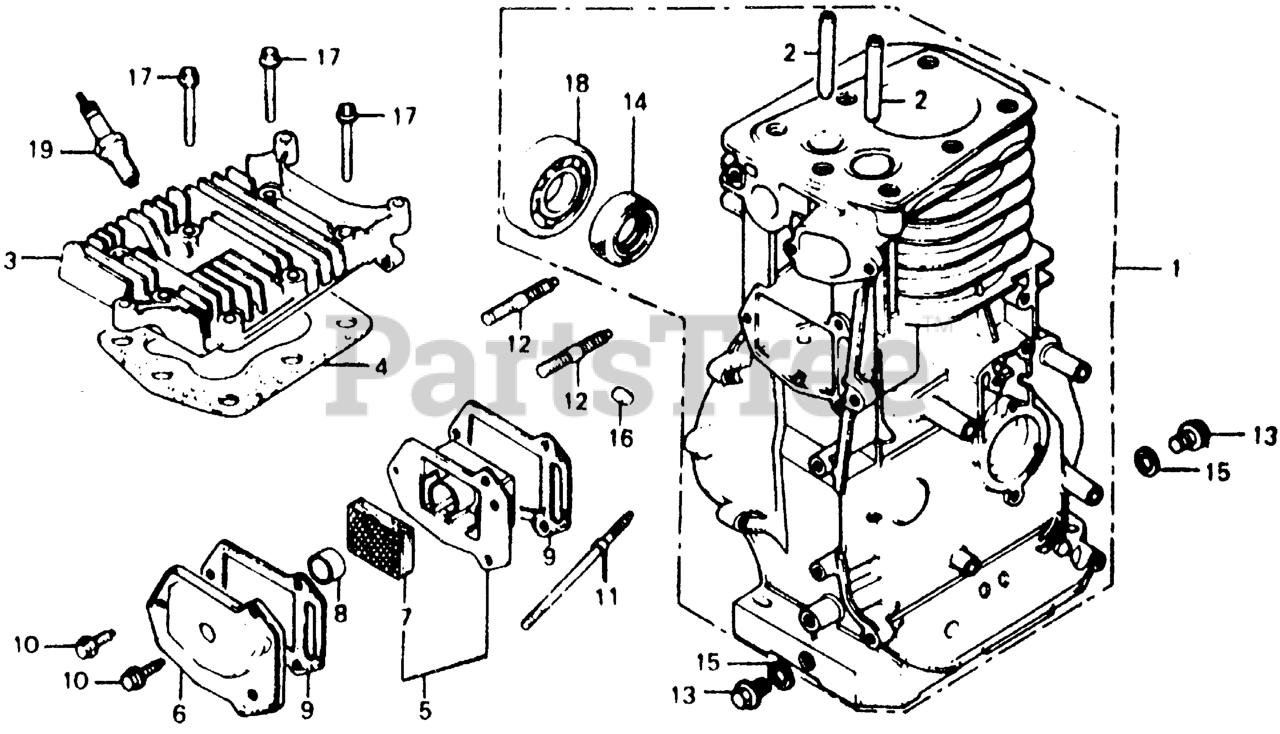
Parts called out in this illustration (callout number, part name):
1	CYLINDER ASSY.
2	GUIDE, VALVE (OVER SIZE)
3	CYLINDER HEAD
4	GASKET, CYLINDER HEAD
5	CASE, BREATHER
6	COVER, TAPPET ROOM
7	FILTER, BREATHER
8	SEAL, BREATHER
9	GASKET, TAPPET COVER Use up to Engine SN 1556857.
10	BOLT, FLANGE (6X12) (CT200)
11	BOLT, STUD (6X96)
12	BOLT, STUD (8X35)
13	BOLT, DRAIN PLUG
14	OIL SEAL (25X41X6)
15	WASHER, DRAIN PLUG (12MM)
16	PIN A, DOWEL (8X14)
17	BOLT, FLANGE (8X45)
18	BEARING, RADIAL BALL (6205)
19	SPARK PLUG (BR-4HS) (NGK)
